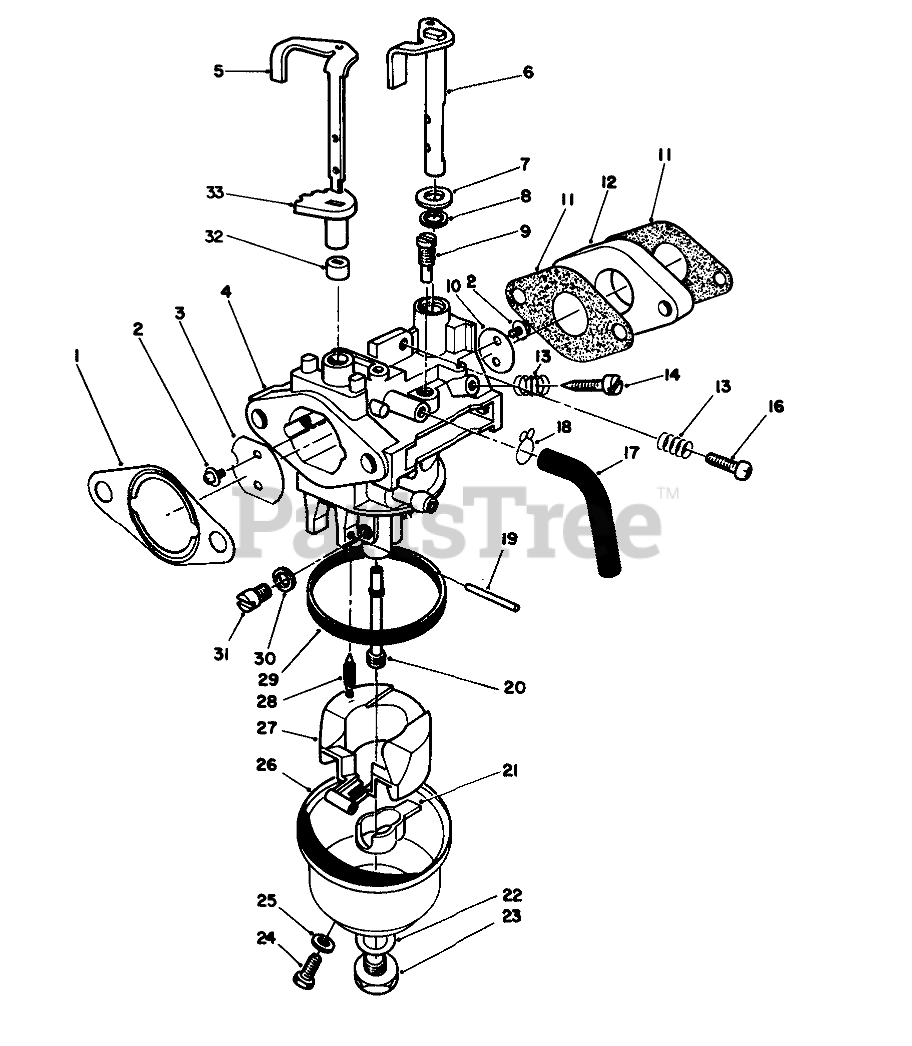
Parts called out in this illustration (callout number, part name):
1	GASKET F/W ENGINE
2	Screw
3	VALVE
4	Body-Carburetor
5	Shaft-Choke Valve
6	SHAFT
7	WASHER
8	Seal-Throttle Shaft
9	JET - PILOT
10	VALVE
11	GASKET INTAKE
12	INSULATOR - CARB.
13	SPRING-PILOT SCREW
14	ADJUSTER
16	SCREW
18	CLAMP
19	Pin
20	NOZZLE - MAIN
21	SPACER
22	GASKET
23	SCREW
24	SCREW
25	GASKET
27	FLOAT
28	NEEDLE
29	FLOAT BOWL GASKET
30	SPACER
31	JET - MAIN
32	LOWER CHOKE RING
33	UPPER CHOKE RING
